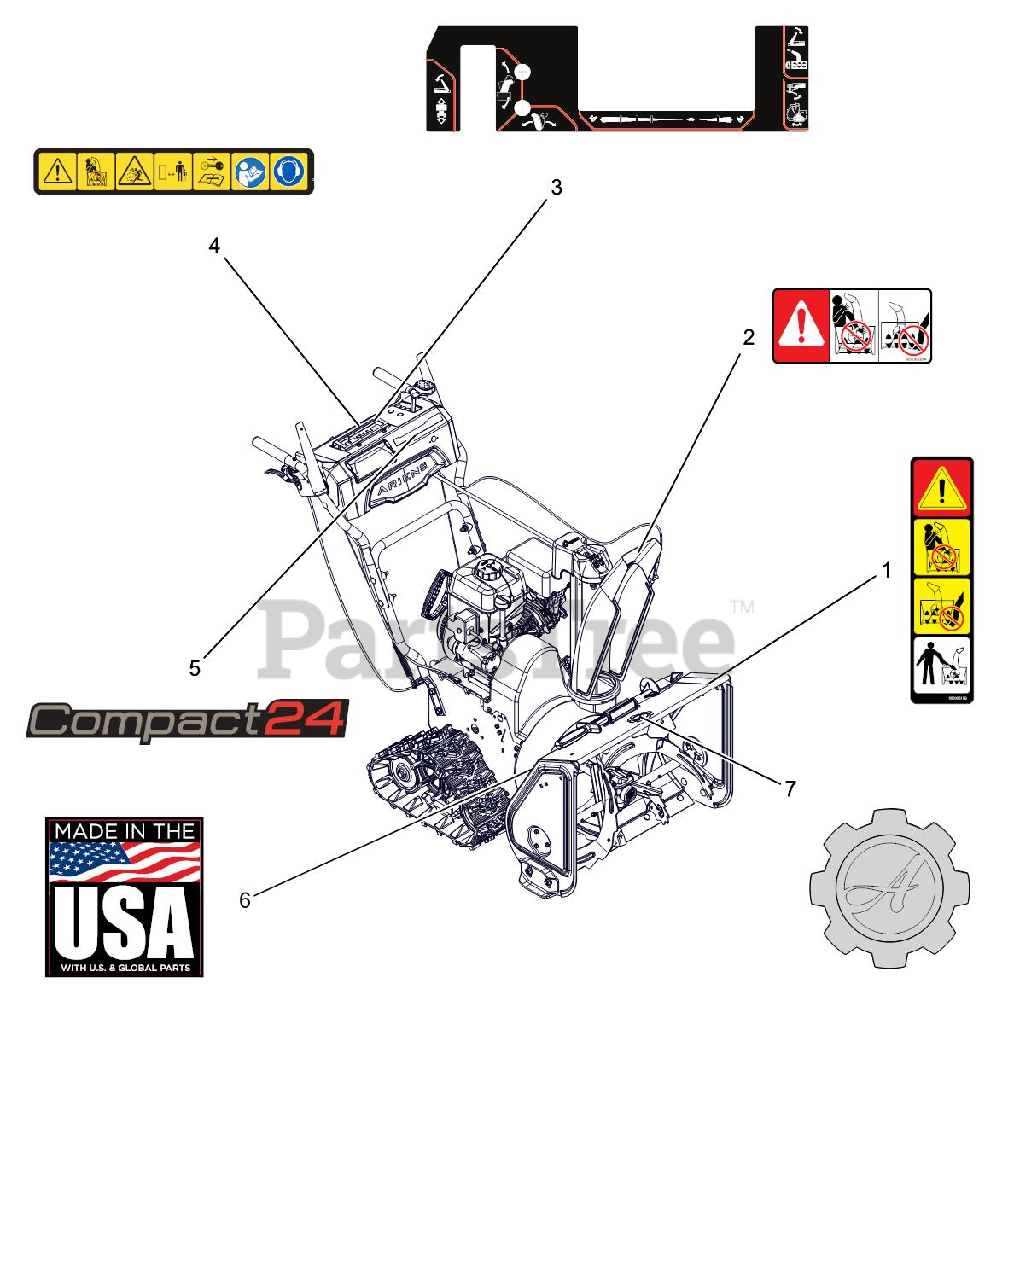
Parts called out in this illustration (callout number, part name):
1	DECAL, DANGER - ROTATING PARTS
2	DECAL, DANGER
3	DECAL,CONTROL-COMP TRACK
4	DECAL,DASH - SAFETY
5	DECAL, DASH - COMPACT 24
6	DECAL, MADE IN USA
7	DECAL, ARIENS-GEAR BADGE
